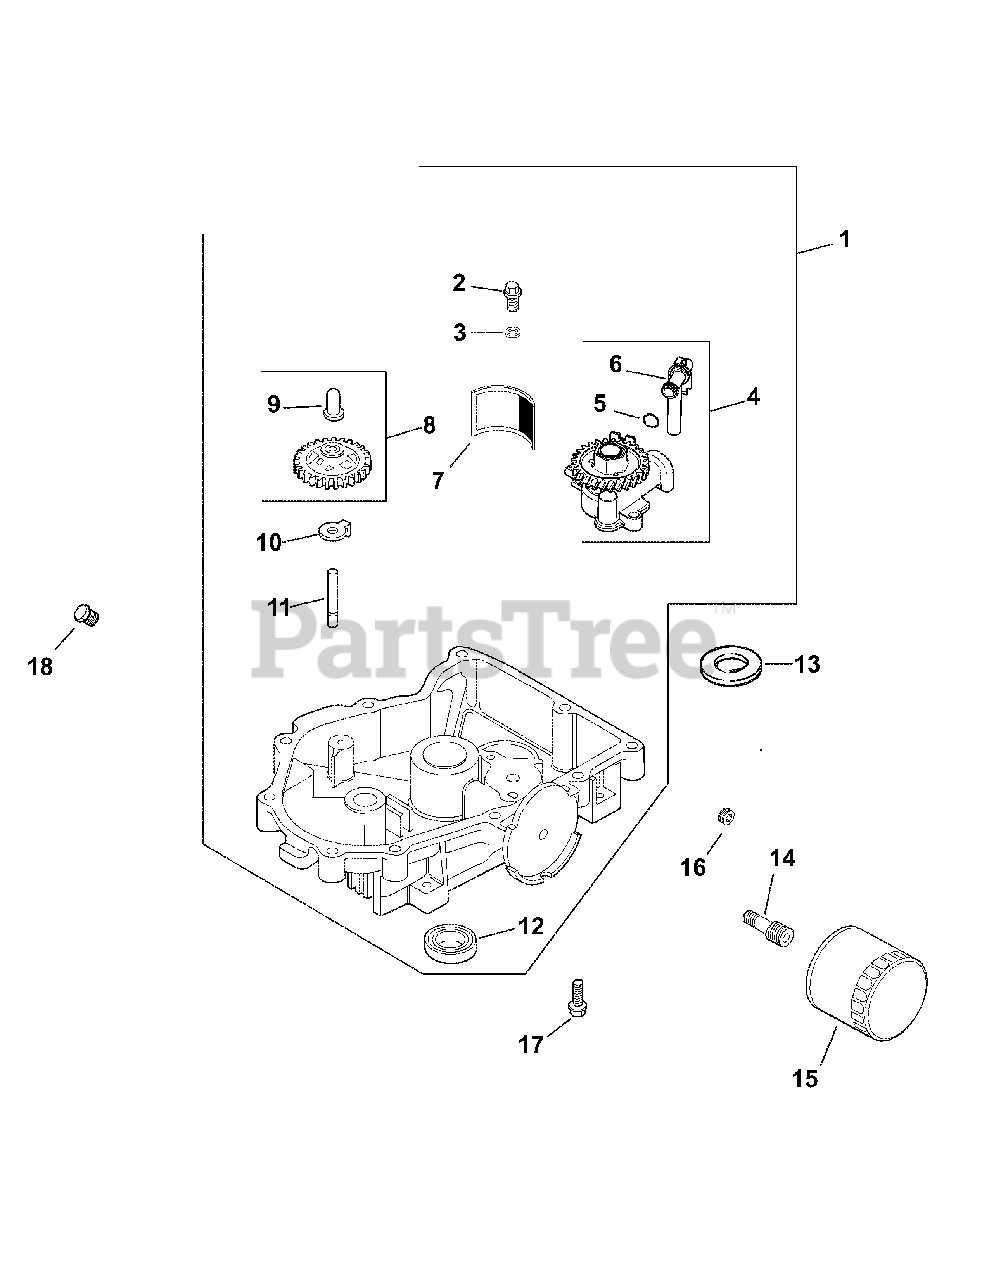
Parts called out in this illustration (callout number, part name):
1	Pan, Oil Assembly
2	Screw, SHD THD FRM M6 x 1.0 x 25
3	Washer, Flat 6MM
4	Kit, Oil Pump Assembly
5	O-Ring, Oil Pick-Up
6	Tube, Oil Pick Up
8	Kit, Governor Gear w/ Pin
9	Pin, Governor Regulating
11	Shaft, Governor Gear
14	Nipple, Oil Filter
16	Plug, Pipe CTSK 3/8"
17	Screw, Flg M8 x 1.25 x 45
18	Plug, Hd Pipe 3/8"
